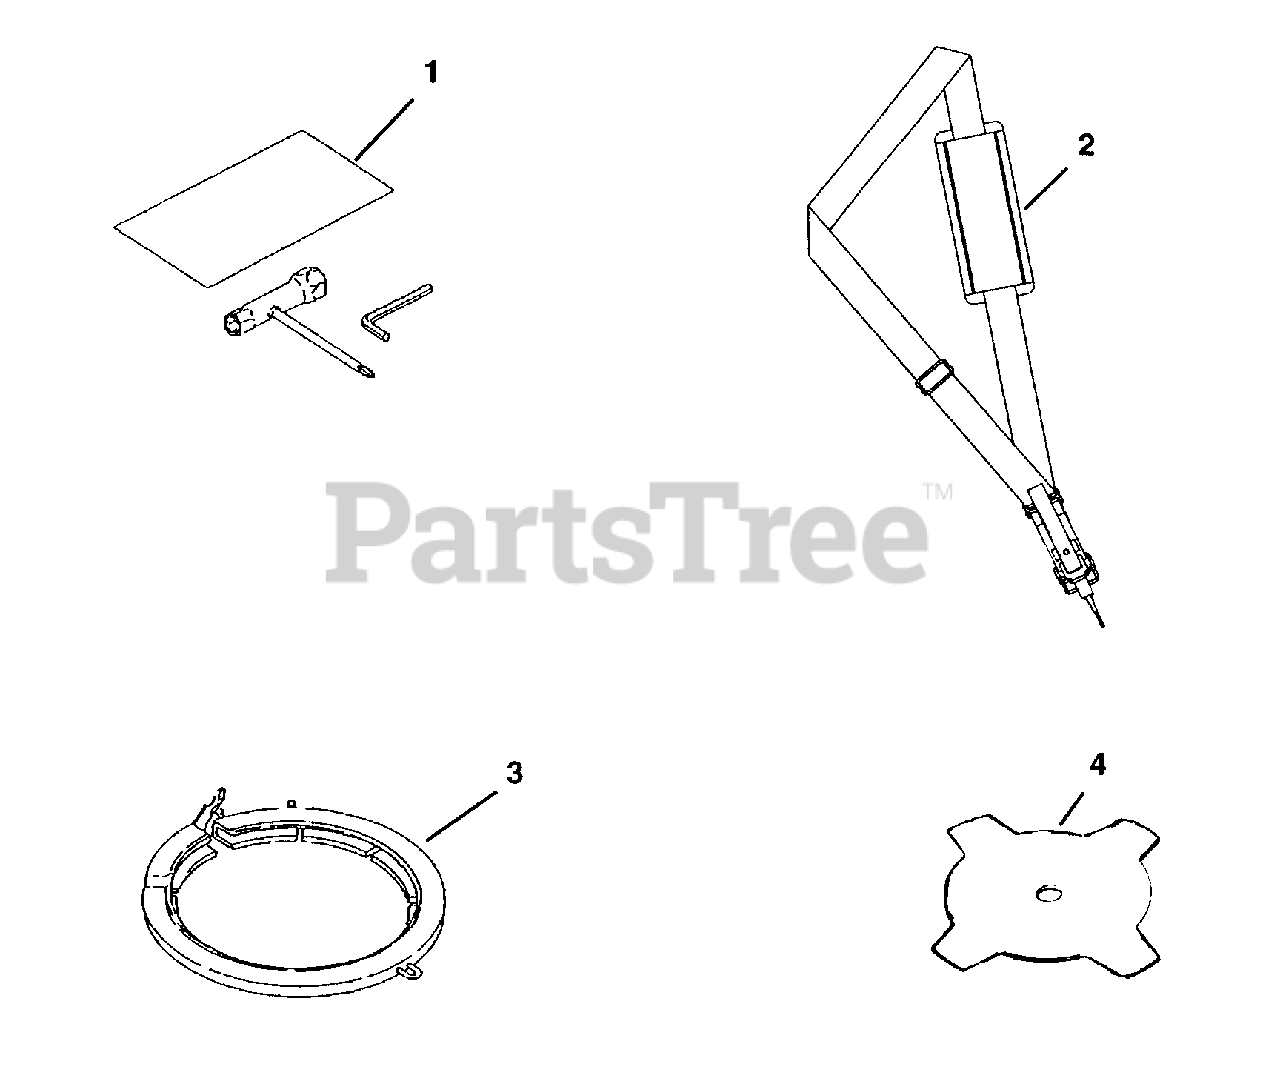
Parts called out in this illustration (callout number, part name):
1	TOOL KIT
3	BLADE COVER
4	QUAD BLADE
